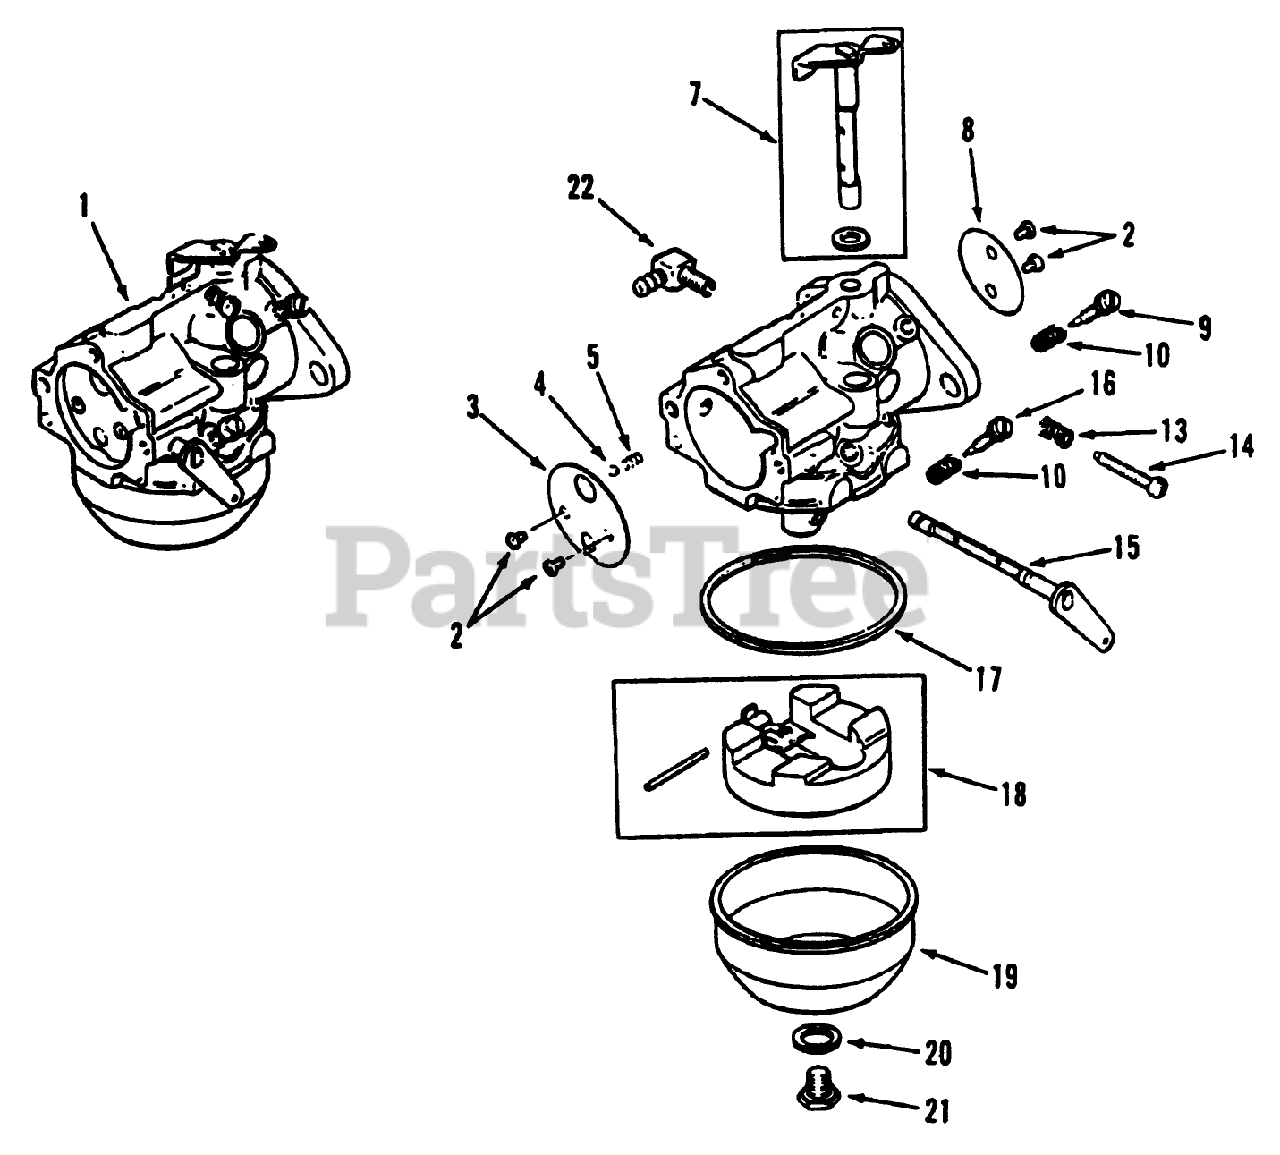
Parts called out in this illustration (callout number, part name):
1	KOHLER 47-853-20
2	KOHLER 25-086-27
3	KOHLER 47-146-08
4	KOHLER 25-194-01
5	KOHLER 25-089-03
7	KOHLER 457-144-21
8	KOHLER 25-146-02
9	KOHLER 25-368-01
10	KOHLER 25-089-02
13	KOHLER 25-089-04
14	KOHLER 25-086-26
15	KOHLER 47-090-38
16	Main-Needle
17	KOHLER 25-041-04
18	KOHLER 25-757-09
19	KOHLER 25-104-01
20	KOHLER 25-041-03
21	KOHLER 25-100-05
